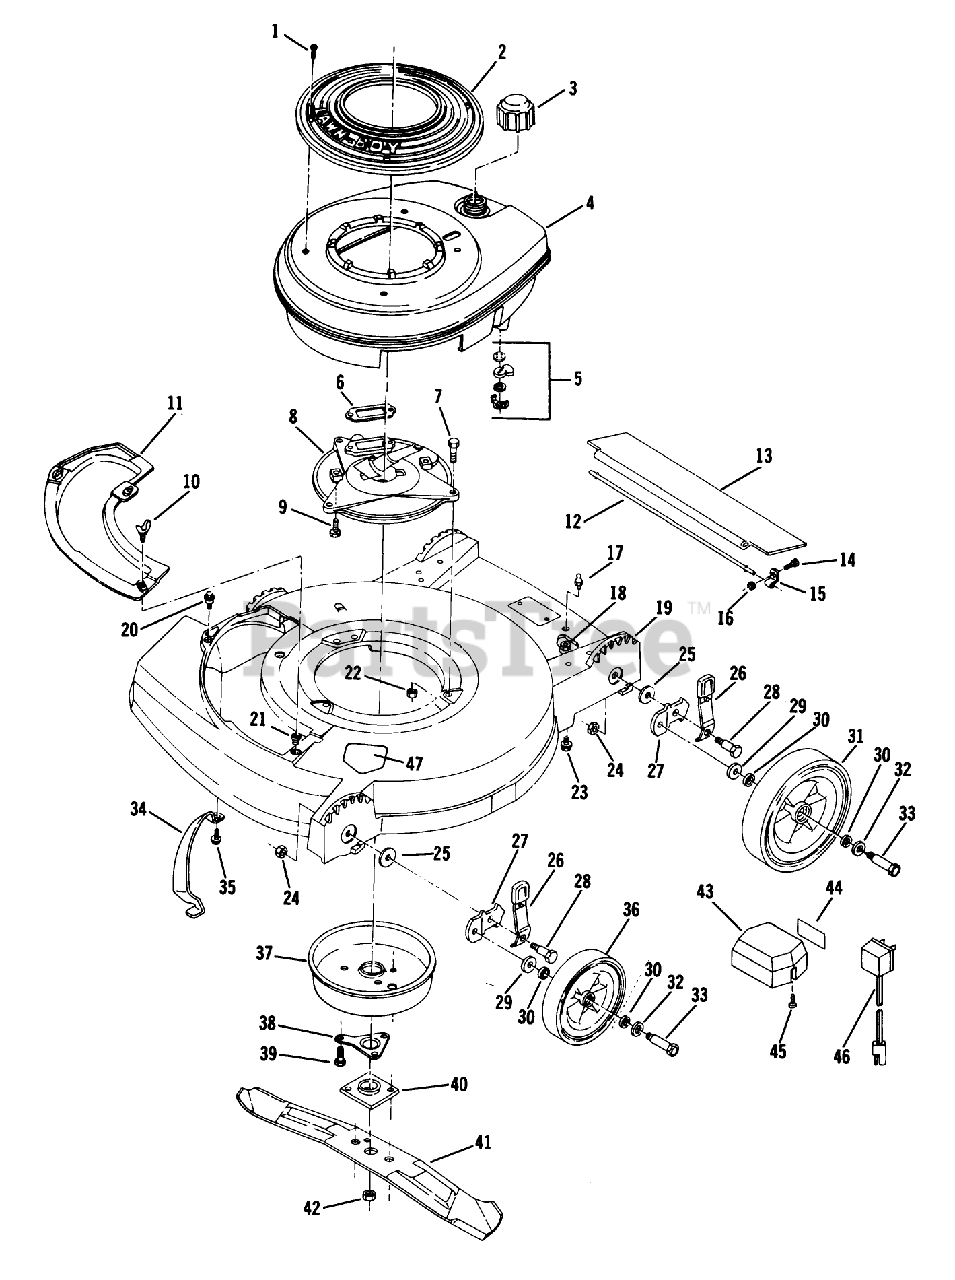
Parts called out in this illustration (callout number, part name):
1	SCREW - SELF TAPPING
3	FUEL CAP & INSERT
5	SHUT OFF VALVE KIT
7	SCREW
9	SCREW V
10	WING SCREW LAWRE
12	ROD 21" ADVANCE
15	CLAMP ROD KMC
16	LOCKNUT E
22	NUT-LOCK F
23	SCREW
24	LOCKNUT
25	WASHER
29	WASHER WROUGHT
30	WASHER
32	SPACER
33	BOLT WHEEL
34	BAR-TOE
36	WHEEL & TIRE KIT
37	MUFFLER COVER F
38	SUPPORT F
39	SCREW
40	PLATE AND COLLAR ASM
42	NUT-BLADE
